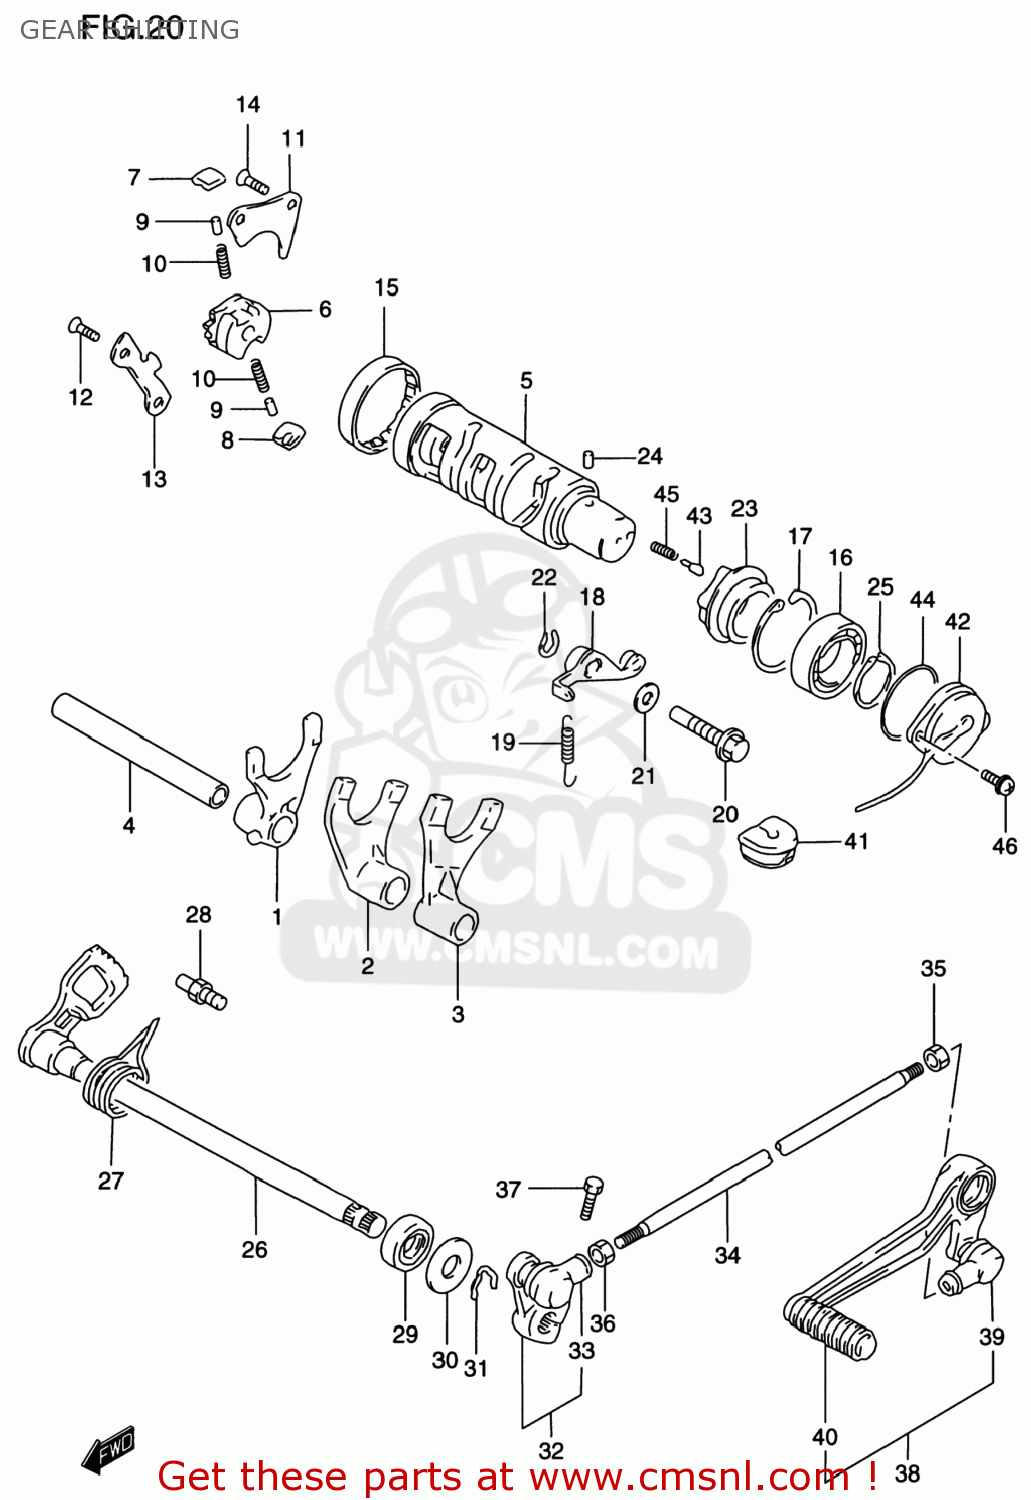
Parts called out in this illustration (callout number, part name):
1	FORK,GEAR SHIFT NO.1
2	FORK,GEAR SHIFT NO.2
3	FORK,GEAR SHIFT NO.3
4	SHAFT,GEAR SHIFT FORK(L:128)
5	CAM,GEAR SHIFT
6	GEAR,GEARSHIFT CAM DRIVE
7	PAWL,GEAR SHIFT NO.1
8	PAWL,GEAR SHIFT NO.2
9	PIN(5X8)
10	SPRING
11	LIFTER,GEAR SHIFT PAWL
12	SCREW
13	GUIDE,GEAR SHIFT CAM
14	SCREW
15	BEARING(43X49X12)
16	BEARING
17	CIRCLIP
18	STOPPER,GEAR SHIFT CAM
19	SPRING
20	SHAFT,GEAR SHIFT CAM STOPPER
21	GASKET(10X14X3.6) (NAS)
22	CIRCLIP
23	PLATE,STOPPER
24	PIN
25	CIRCLIP
26	SHAFT,GEAR SHIFT
27	SPRING
28	STOPPER,GEAR SHIFT CAM
29	OIL SEAL
30	WASHER (12.5X27X1.6)
31	CIRCLIP,12 MM
32	ARM,GEAR SHIFT LINK
33	COVER,DUST
34	ROD,GEAR SHIFT LINK
35	NUT
36	NUT
37	BOLT
38	LEVER ASSY,GEAR SHIFT
39	COVER,DUST
40	RUBBER,GEAR SHIFT PEDAL
41	GROMMET,LEADWIRE
42	TERMINAL BASE ASSY,NEUTRAL
43	PIN(5X15.5)
44	O RING(D:2.4,ID:35.5)
45	SPRING
46	SCREW
